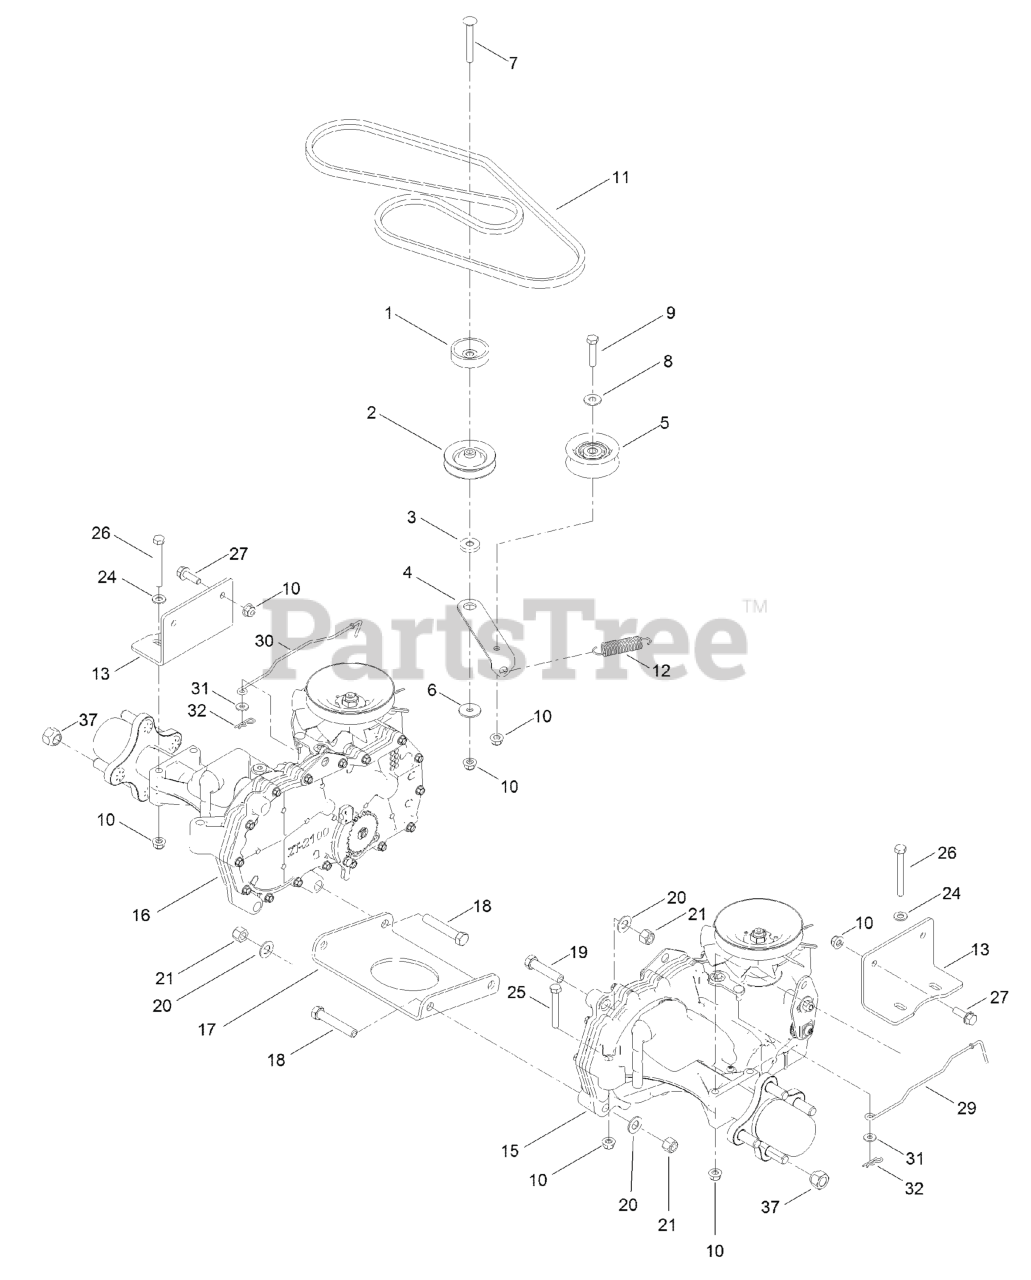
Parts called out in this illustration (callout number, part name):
2	PULLEY-IDLER
3	SPACER-ARM, IDLER
4	Arm-Idler
5	Pulley-Idler, Flat
6	WASHER-PIVOT
7	SCREW-CARR
8	WASHER-FLAT
9	SCREW-HH
10	NUT-HF, NI
11	V-BELT
12	Spring-Return, Pedal
13	MOUNT-HYDRO
15	LH HYDRO TRANSAXLE ASM
16	RH HYDRO TRANSAXLE ASM
17	PLATE-CROSS, HYDRO
18	SCREW-HH
19	SCREW-HH
20	WASHER-FLAT
21	NUT-LOCK, NI
24	WASHER-PLAIN
25	SCREW-HH
26	SCREW-HH
27	SCREW-HHF
29	ROD-BYPASS, LH
30	ROD-BYPASS, RH
37	NUT-LUG
